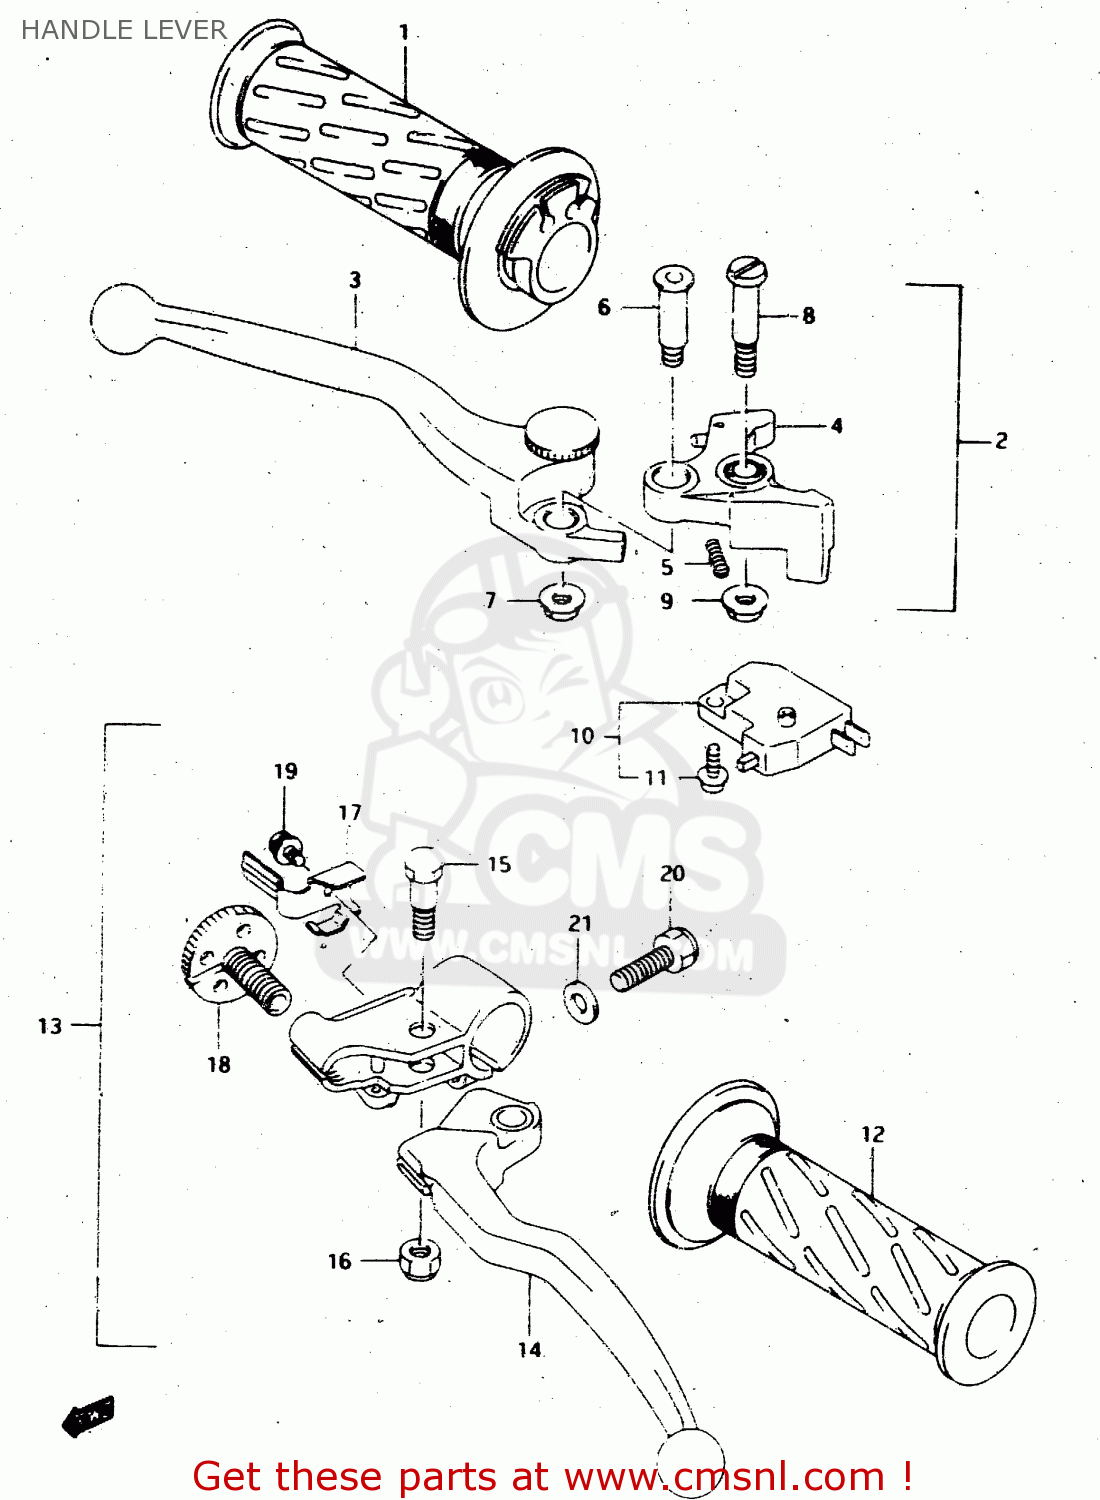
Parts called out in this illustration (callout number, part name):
1	GRIP,THROTTLE
2	LEVER ASSEMBLY,BRAKE
3	LEVER,ADJUST
4	KNOCKER
5	SPRING
6	BOLT,LEVER
7	NUT
8	BOLT,LEVER PIVOT
9	NUT 6MM
10	SWITCH ASSEMBLY,STOP
11	SCREW
12	GRIP,LEFT
13	LEVER ASSY,CLUTCH
14	LEVER,CLUTCH
15	BOLT,LEVER PIVOT
16	NUT
17	ADJUST,SPRING
18	ADJUSTER,LOCK
19	SCREW
20	BOLT
21	WASHER
